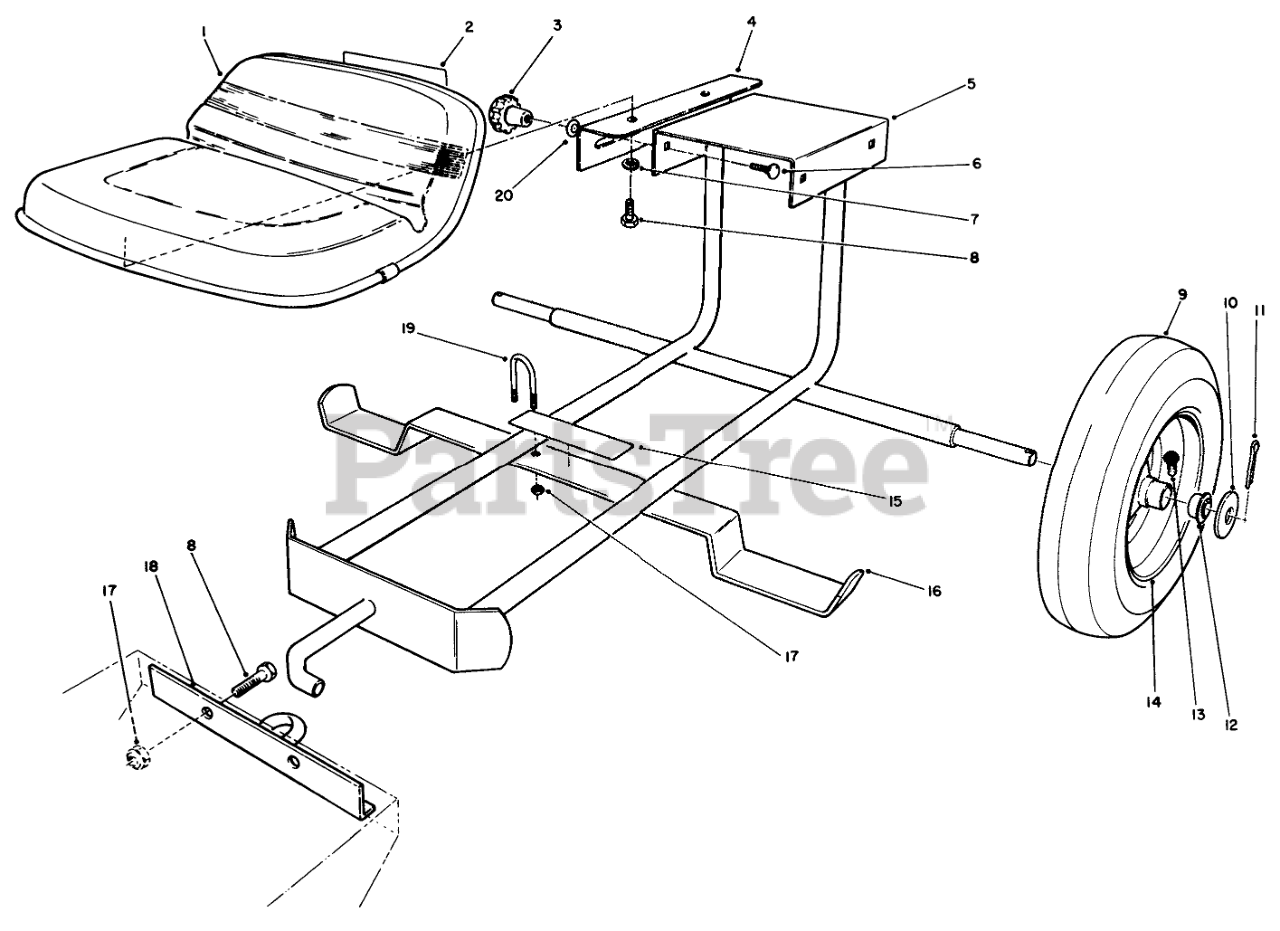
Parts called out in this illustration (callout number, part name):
1	Seat
2	DECAL
4	BRACKET R
5	Frame Assembly
6	BOLT-CARR
7	WASHER-LOCK
8	SCREW-HH
10	WASHER-FLAT
11	PIN-COTTER
12	BEARING
13	VALVE STEM-INNER TUBE
14	WHEEL
15	SULKY DECAL
16	SULKY FOOTREST R
17	NUT-LOCK, NI
18	HITCH
19	U-BOLT
20	WASHER-BELLEVILLE
